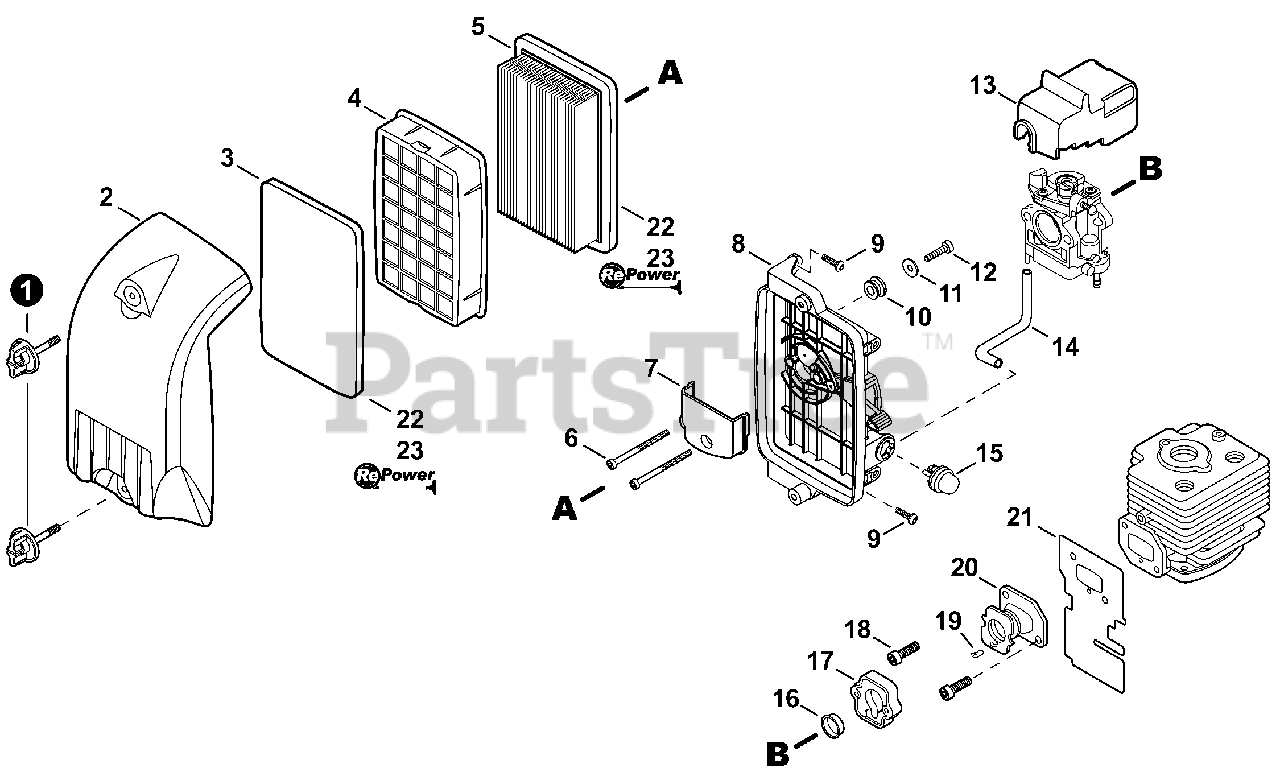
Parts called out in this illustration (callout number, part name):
1	THUMBSCREW
2	COVER, AIR FILTER
3	PRE-FILTER, FOAM
4	RETAINER, PRE-FILTER
5	FILTER, AIR
6	BOLT, TORX 5×55
7	PLATE, PREVENT
8	CASE ASSY, AIR FILTER
9	BOLT, TORX 5×20
10	GUIDE, CABLE
11	WASHER 5.5×16×0.8
12	BOLT, TORX 5×16
13	CAP, CARBURETOR
14	PIPE, PURGE 2.5×5×140
15	BULB, PURGE
16	RING, SEAL
17	ADAPTOR, INTAKE
18	SCREW 5×12
19	COLLAR 3
20	BELLOWS, INTAKE
21	HEAT SHIELD, INTAKE
22	TUNE-UP KIT - REPOWER
23	FILTER KIT - REPOWER
